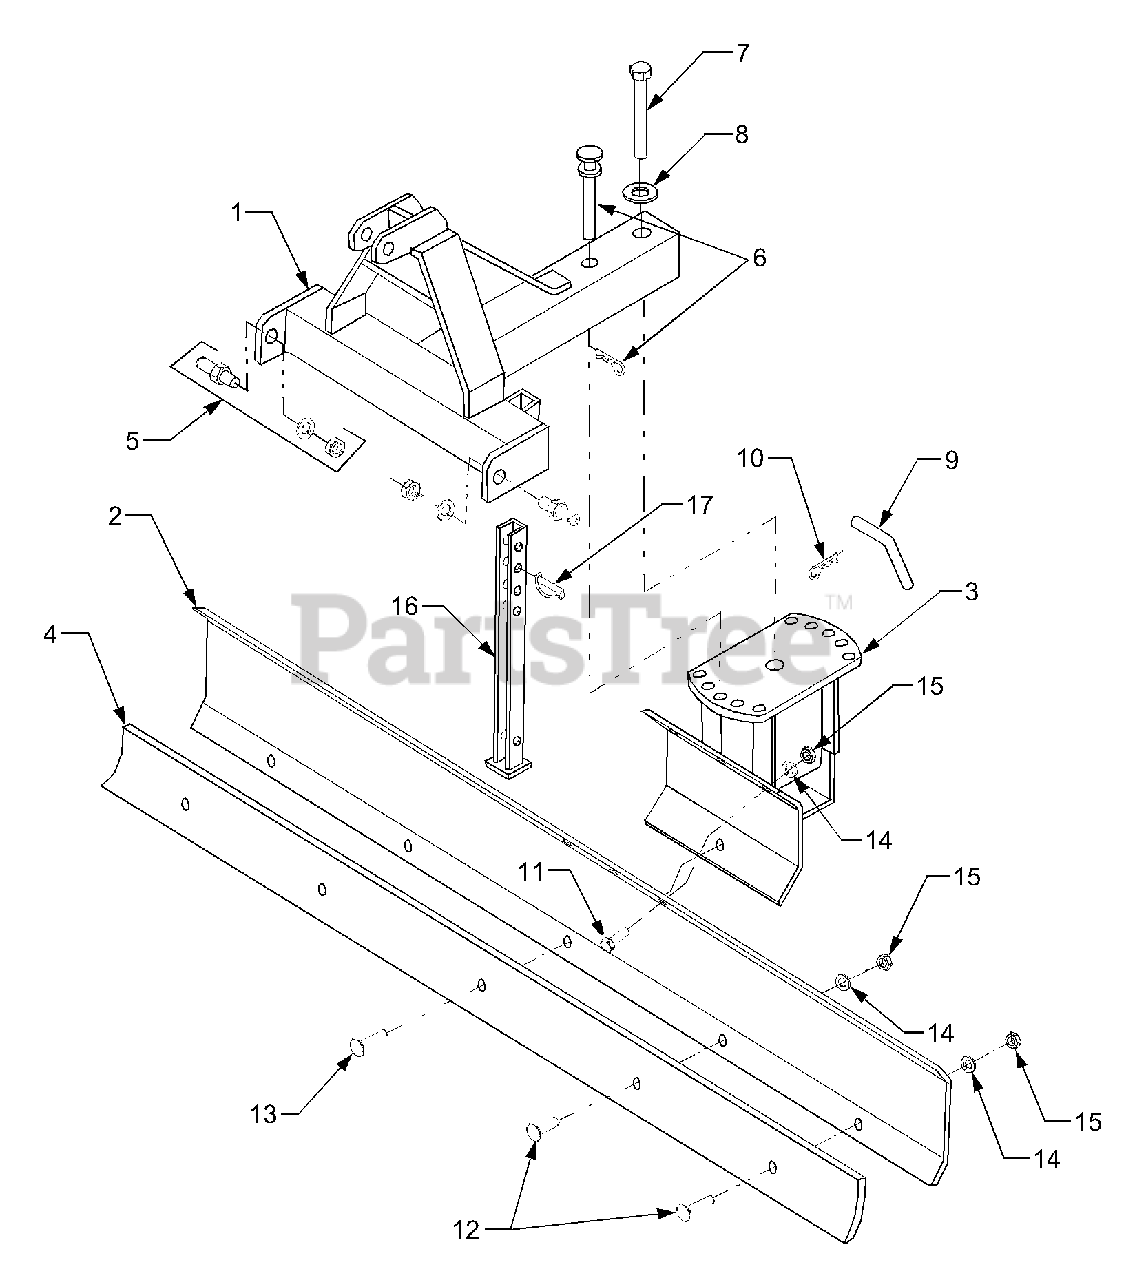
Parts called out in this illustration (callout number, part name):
4	Scraper Blade
5	Hitch Pin w/Lockwasher and Nut, 7/8
6	Swivel Pin w/Cotter Pin
7	Hex Bolt, 1.0 x 6.0
8	Flat Washer, 1.0 ID
11	Hex Bolt, 5/8-11 x 2.0
12	Plow Bolt, 5/8-11 x 1.5
13	Plow Bolt, 5/8 x 2.0 GR5
14	Lockwasher, 5/8
15	Hex Nut, 5/8
